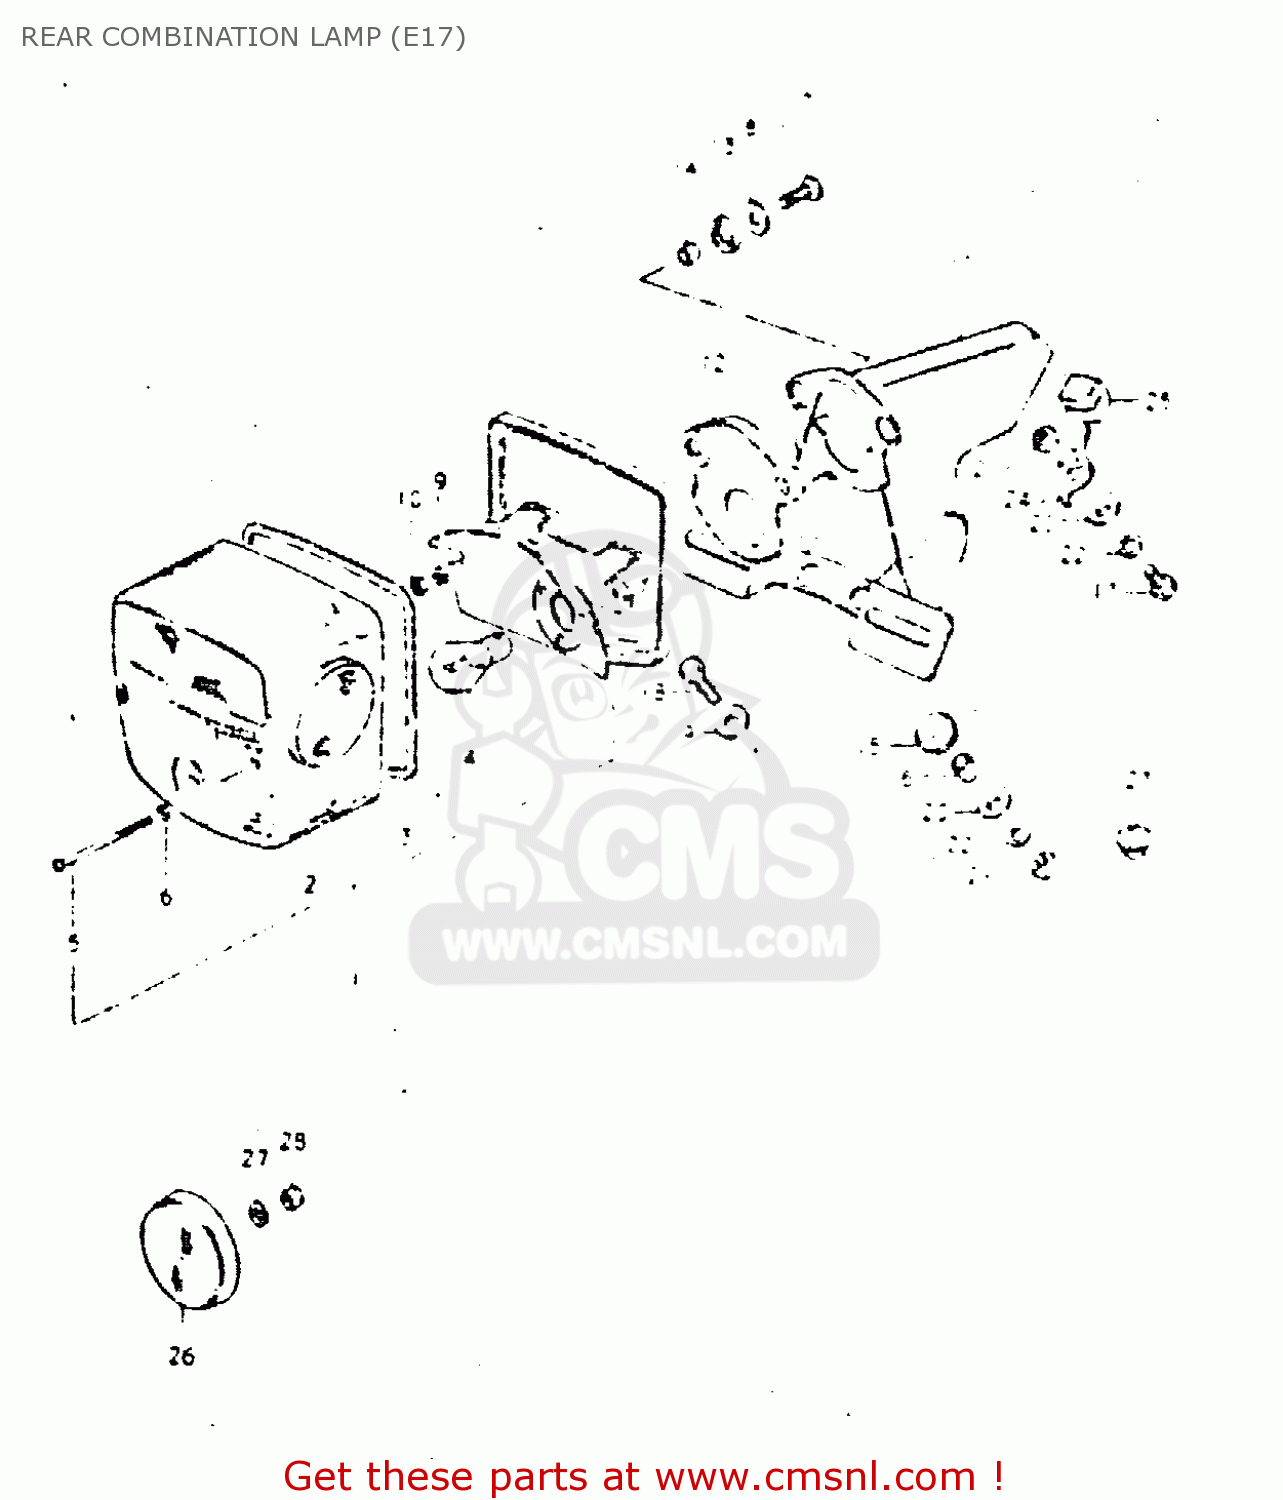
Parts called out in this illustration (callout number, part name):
1	LAMP UNIT, TAIL
2	LENS
3	GASKET (NAS)
4	BULB (6V,21/5W)
5	SCREW (4X55)
6	GASKET (NAS)
7	SCREW
8	WASHER,REAR COMBINATION LAMP
9	NUT
10	LOCK WASHER
11	BRACKET SET
12	CUSHION
13	CUSHION
14	SPACER,REAR COMBINATION LAMP
15	CUSHION,REAR COMBINATION LAMP
16	SPACER
17	BOLT
18	BOLT
19	WASHER (6.5X20X1.2)
20	WASHER
21	NUT
22	WASHER
23	GROMMET
24	PLATE
25	CUSHION
26	REFLECTOR,REFLEX
27	WASHER
28	NUT
